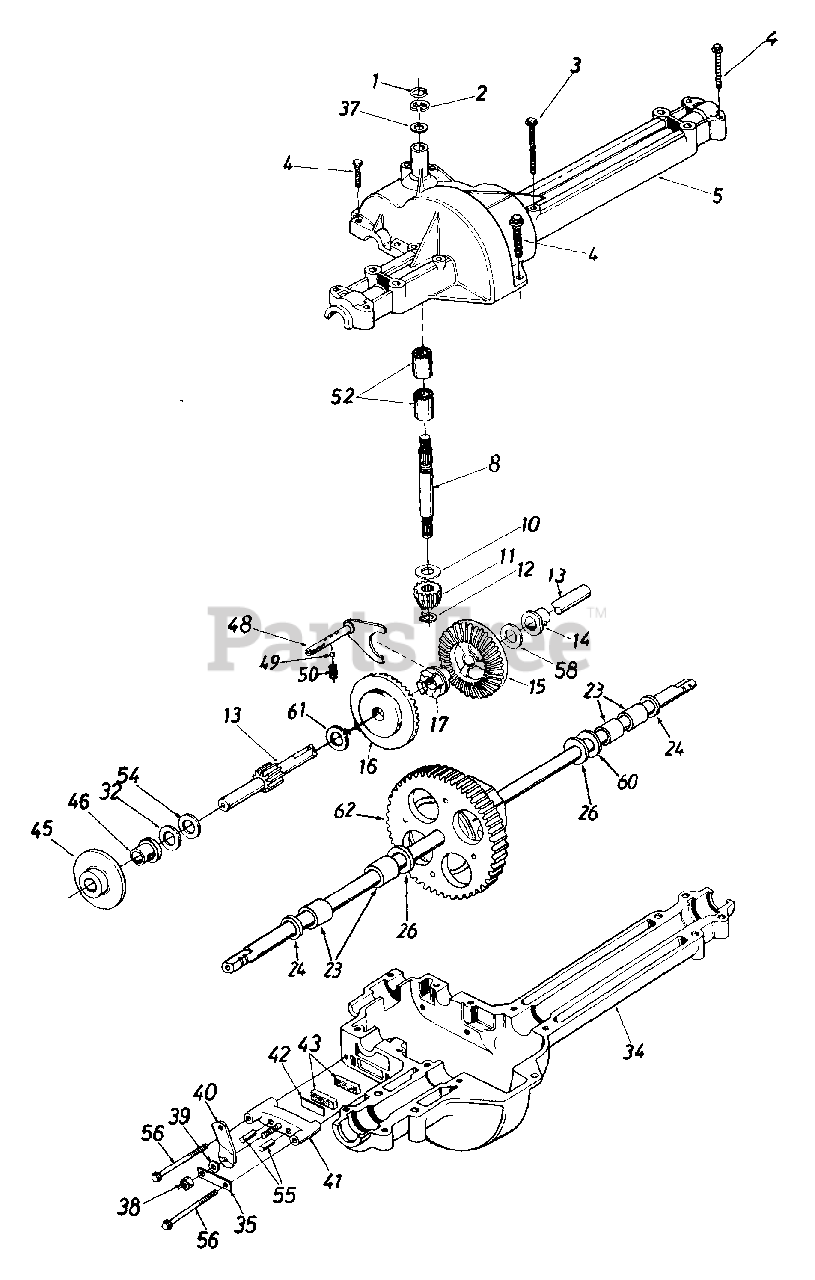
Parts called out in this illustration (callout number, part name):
1	Wire Ring
3	Hex Wash. TT-Tap 1/4-20 x 1.75" Lg.
4	Hex Tap Scr. 1/4-20 x 1.25" Lg.
5	Upper Housing
8	Input Shaft
10	Thrust Washer 5/8" I.D. x 1.25" O.D.
11	Pinion Input 14T
12	Retaining Ring
13	Drive Shaft - L.H. Brake
14	Flange Brg. 5/8" I.D. x 3/4" Lg.
15	Bevel Gear 42T - Small I.D.
16	Bevel Gear 42T - Large I.D.
17	Clutch Collar
23	Sleeve Bearing 3/4" I.D. x 1.0" Lg.
24	Oil Seal 3/4" I.D.
26	FI-Wash..760" I.D. x 1.5" O.D.
32	Thrust Wash. 5/8" I.D. x 1" O.D. x .025" Thk.
34	Lower Housing
35	Anti-Rotation Brkt.
37	Fl-Wash. 5/8" I.D. x 1" O.D. x .020" Thk.
38	Hex Nut 5/16-24 Thd.
39	FI-Wash..344" I.D. x.875" O.D.
40	Actuating Arm
41	Brake Yoke
42	Puck Plate
43	Brake Puck
45	Brake Disc
46	Flange Bearing 5/8" I.D. x 15/16" Lg.
48	Shift Fork Ass'y.
49	Ball Detent .250" Dia.
50	Spring Detent
52	Needle Brg 5/8" I.D. x 1/2" Lg.
54	Fl-Wash. 5/8" I.D x 1" O.D. x .020 Thk.
55	Actuating Pin 5/16" Dia.
56	Hex Wash Hd. Self-Tap Scr. 1/4-20 Thd.
58	Fl-Wash. 5/8" I.D. x 1" O.D. x .020 Thk.
60	FI-Wash..76" I.D. x 1.5" O.D. x .010" Thk.
61	Thrust Washer
62	Differential Ass'y.
